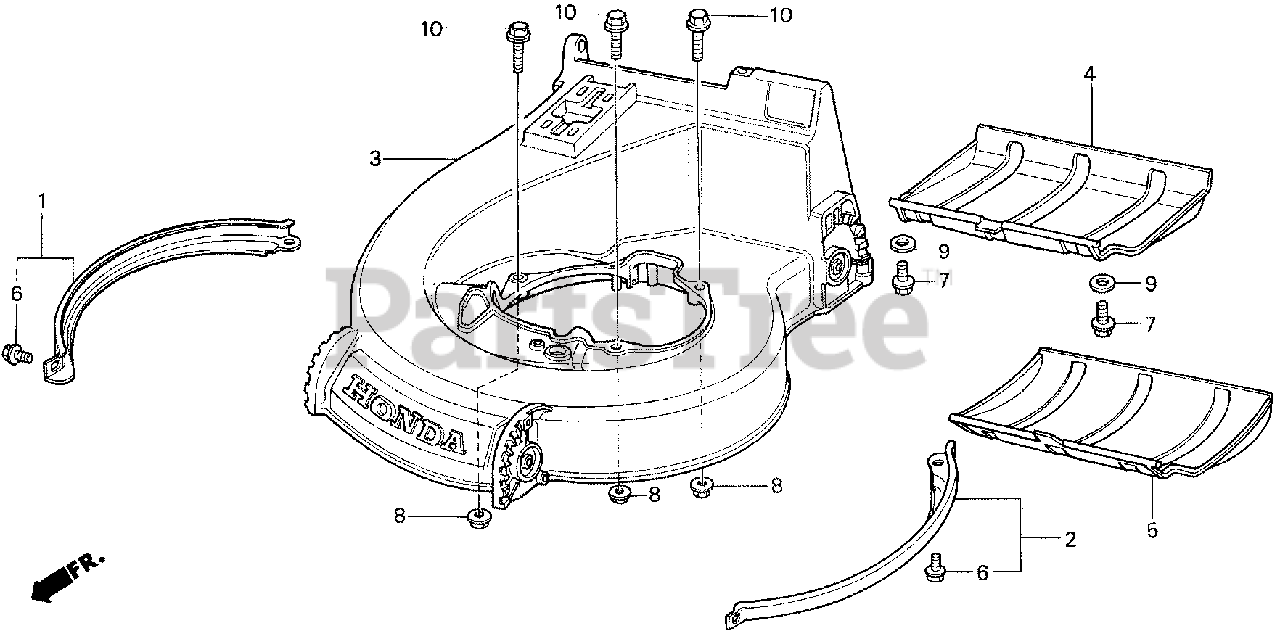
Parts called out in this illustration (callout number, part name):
1	GUARD SET, R. HOUSING (NOT AVAILABLE)
2	GUARD SET, L. HOUSING (NOT AVAILABLE)
3	HOUSING, CUTTER
4	SHIELD, SAFETY (NOT AVAILABLE)
5	SHIELD, SAFETY (NOT AVAILABLE)
6	BOLT, FLANGE (6X12) (CT200)
7	BOLT, FLANGE (6X25) (CT200)
8	NUT, FLANGE (8MM)
9	WASHER, PLAIN (6MM)
10	BOLT, FLANGE (8X35)
